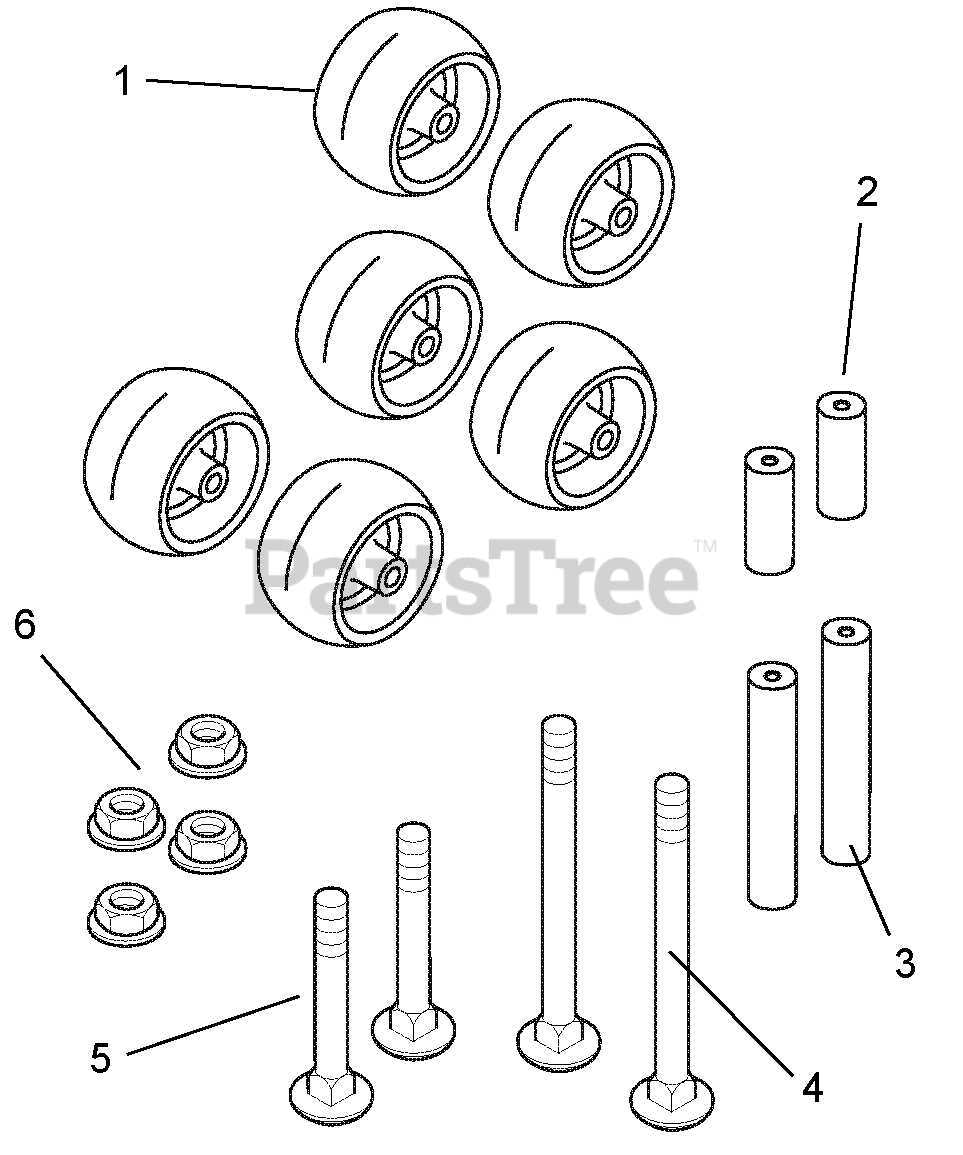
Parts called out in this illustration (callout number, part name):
1	Roller, Anti-Scalp
2	Spacer, .510 x .625 x 3.35
3	Spacer, .510 x .625 x 6.70
4	Bolt, Roundhead Squareneck .50-13 x 8.50
5	Bolt, Roundhead Squareneck .50-13 x 5.00
6	Nut, .50-13 Nyloc Flange
